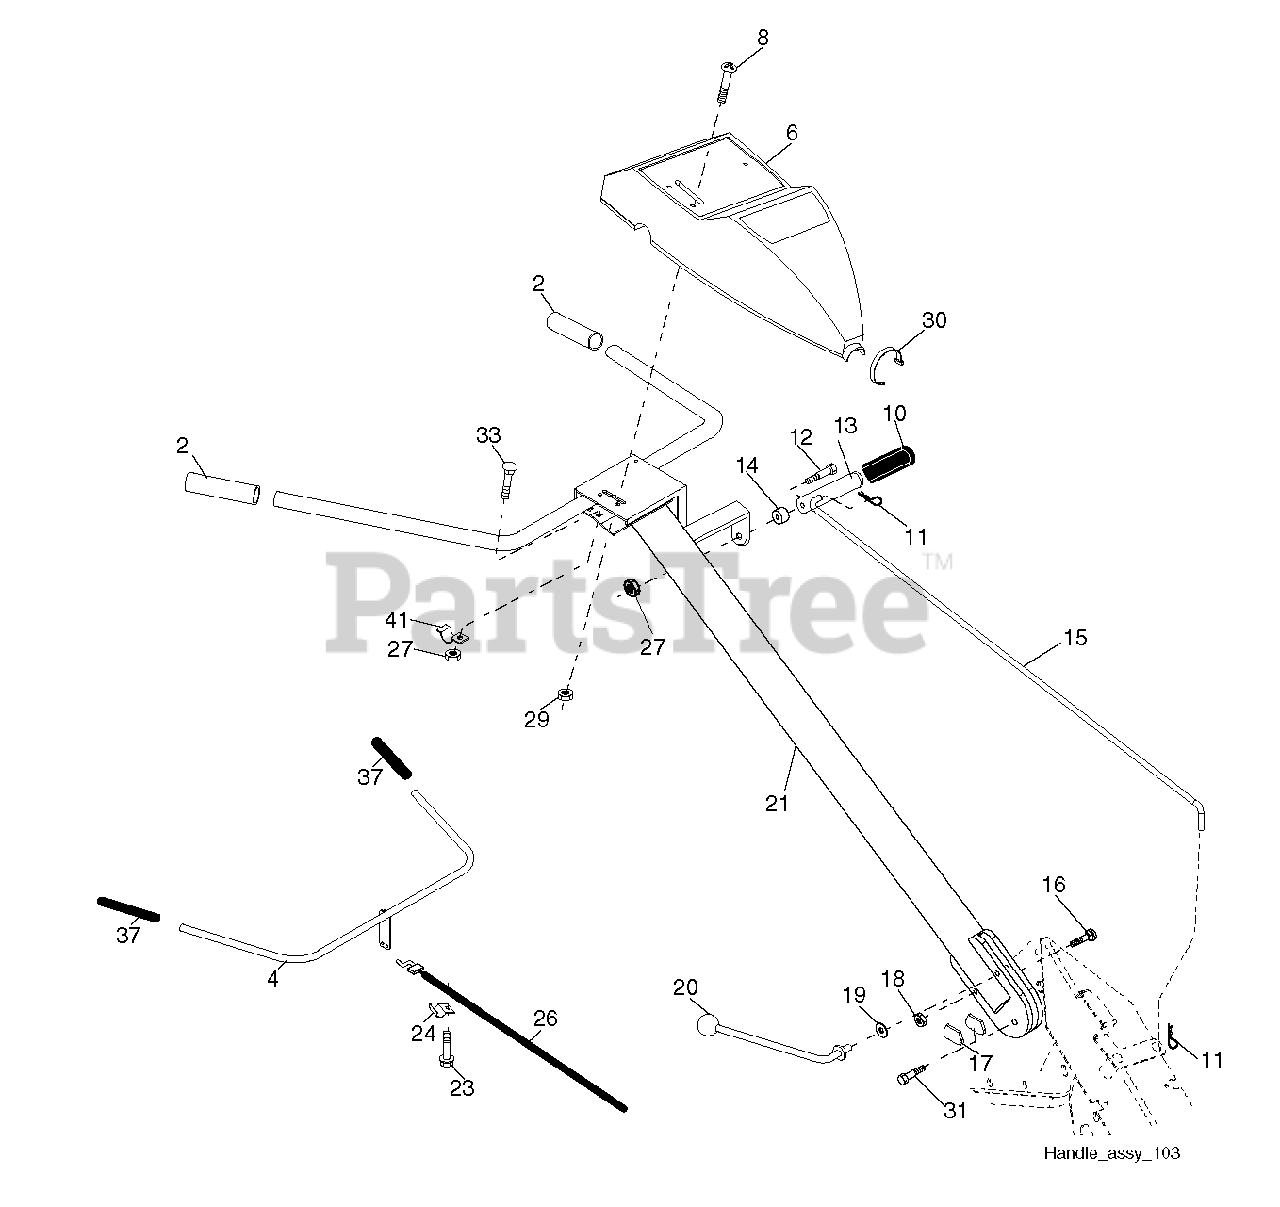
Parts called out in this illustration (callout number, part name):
2	GRIP.1X5.06
4	CONTROL BAR ASSY
6	PANEL.CONTROL.BLACK.NO.SLOT
8	SCREW.PNHD.10-24
10	GRIP T
12	SHOULDER BOLT ST
13	HANDLE.SHIFT.TILLER
14	GROMMET.RUBBER.CRT.TILLER
15	SHIFT ROD CRT
17	LOCK.HANDLE.CRT
18	LOCKNUT
19	WASHER CRT
20	LEVER.LOCK.CRT
21	HANDLE.ASM.TILLER.BLACK
24	CONDUIT CLIP T
26	CABLE.CLUTCH
27	NUT T
29	NUT **
30	TIE CABLE CRT
31	BOLT.PIVOT
37	GRIP BAR CRT(1)
41	CLAMP.BAR.CRT.BLACK
